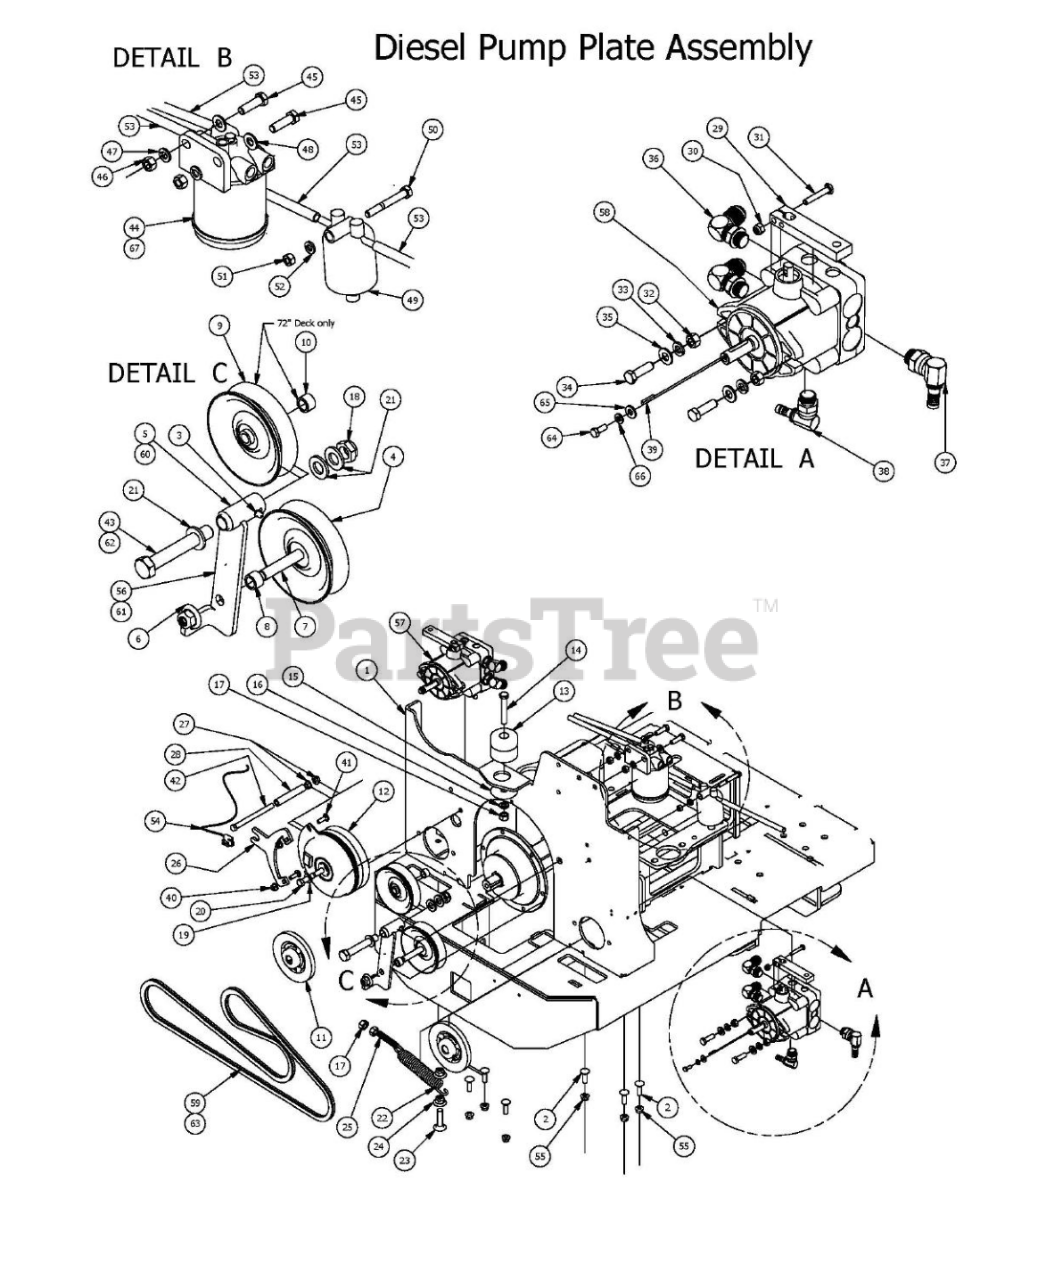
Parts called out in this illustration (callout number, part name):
1	Pump Plate Diesel
2	3/8" x 1 1/4" Carriage Bolt
3	1/4" Drive in Grease Fitting
4	4 3/4" Idler Pulley
5	Pump Idler Bracket only for 61" Deck
6	1/2-13 Nylon Flange Nut-Orange
7	1/2" x 3" Hex Bolt
8	1/2 x 1/2 Spacer
9	5" Idler Pulley only for 72" Deck Diesel
10	5/8" x 1/" Collar Spacer only for 72" Deck Diesel
11	5" Pump Pulley
12	Clutch Assembly for Diesel
13	Armor Plated Mount-Rear Mount
14	1/2" x 3" Hex Bolt
15	Snubbing Washer
16	1/2" Lock Washer
17	1/2" Hex Nut
18	5/8" Nylock (1/2 Jam)
19	7/16" Lock Washer
20	7/16" x 2 3/4" Fine Thread Bolt
21	.630 ID x 1.122 OD x .142 THK Plastic Washer
22	Deck Idler Spring
23	1/2 x 2" Carriage Bolt
24	1/2-13 Nylon Flange Nut-Orange
25	1/2-13 x 2-1/2 All Thd Stud
26	Diesel PTO Engager Holder
27	3/8" Flange Nut
28	3/8 hose 4" long
30	1/4" Nylock Nut
31	1/4" x 1 1/2" Bolt
32	3/8" Hex Nut
33	3/8" Lock Washer
34	3/8" x 1 1/2" Hex Bolt
35	3/8" Flat Washer
36	90 Degree Adaptor 6801-L-8-8 Fitting
37	90 Degree Fitting 1/2" x 3/4" 4601-8-8
38	90 Degree Fitting 3/8" X 9/16"-4601-6-6
39	5mm x 1.25" Key
40	5/16" Flange Nut
41	5/16" x 1" Carriage Bolt
42	3/8-16 x 5 Hex Bolt - Grade 5
43	5/8" x 4" Hex Bolt 61" Deck only
44	Fuel Filter
45	3/8" x 1 1/4" Hex Bolt
46	3/8" Hex Nut
47	3/8" Lock Washer
48	3/8" Flat Washer
49	Caterpillar Fuel Bowl Kit
50	5/16" x 2 1/2" Bolt
52	5/16" Lock Washer
53	5/16" fuel line hose
54	Clutch Pigtail
55	3/8" Nylock Flange Nut
56	Pump Idler Assembly Components 3,4,5,6,7,8, only for 61" Deck
57	Left Pump 16cc AOS Diesel 35Hp Diesel
58	Right Pump 16cc - AOS Diesel 35Hp Diesel
59	Pump Belt for 72" Deck
60	Diesel Pump Idler only on 72" Deck
61	Diesel Pump Idler Assembly Components 3,4,5,6,7,8,9,10 only for 72" Deck
62	5/8 x 5 1/2 Bolt only for 72" Deck
63	Pump Belt for 61" Deck
64	M6-1.0 X 16MM Hex Bolt
65	1/4" Flat Washer
66	1/4" Lock Washer
